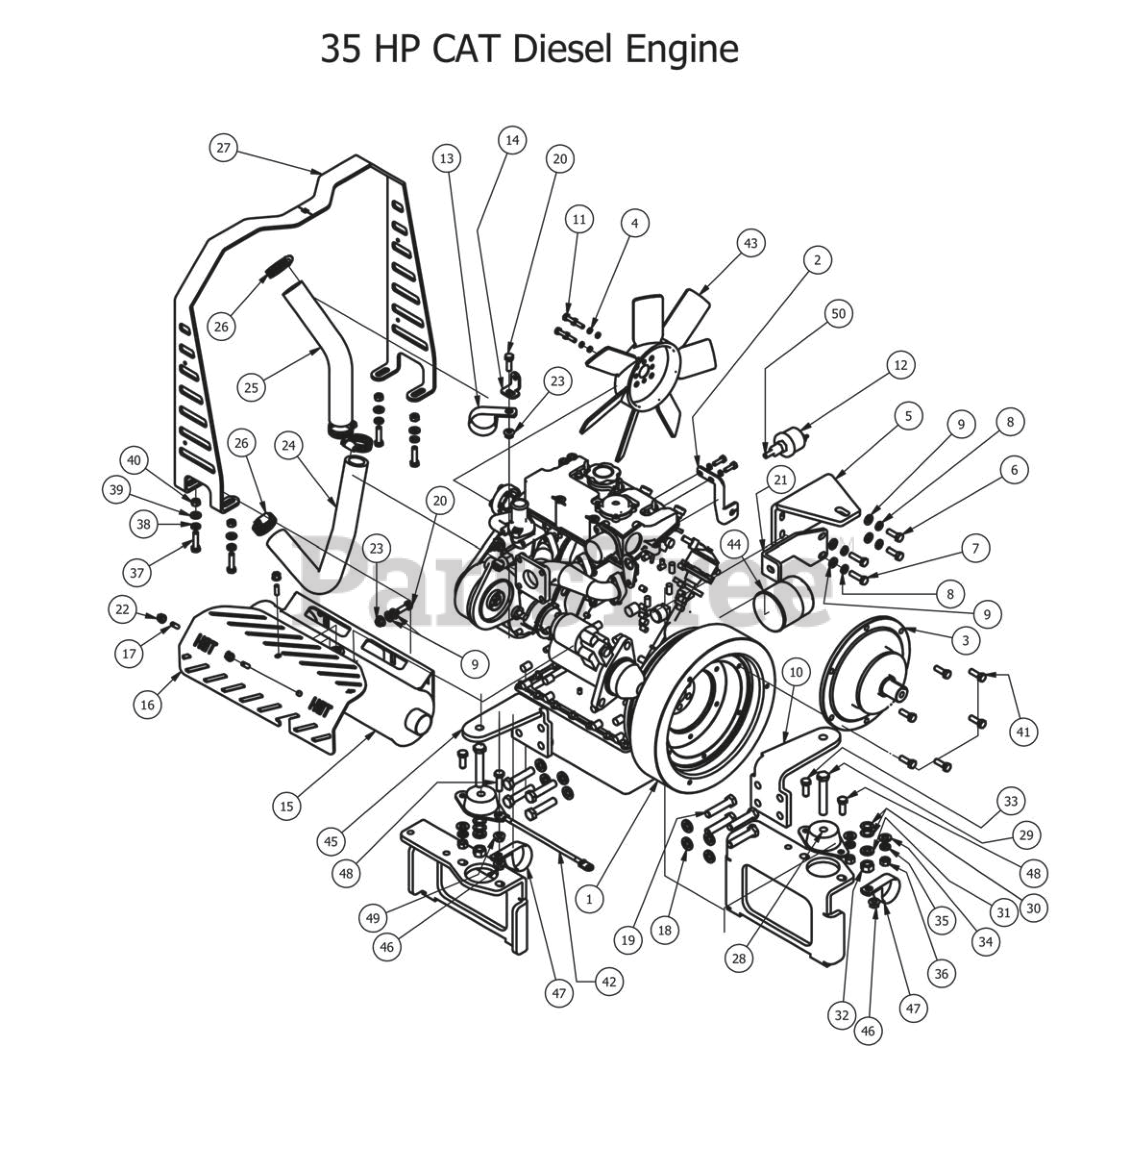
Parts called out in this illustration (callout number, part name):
1	35HP CAT Diesel Engine
2	Diesel Throttle Bracket (4 Tier)
3	Stub Shaft
4	1/4" Lock Washer
5	Air Cleaner Support Diesel
6	M8 x 1.25 x 25mm Hex Head Bolt
7	M8 x 1.25 x 30mm Hex Head Bolt
8	5/16" Lock Washer
9	5/16" Flat Washer
10	Diesel Motor Side Support Right
11	6mm x 20mm Bolt
12	Pressure Sender-2012 Gauge and Up
13	Diesel Clamp 1 3/4" Vinyl
14	Diesel Radiator Hose Clamp Bracket
15	28/35hp Caterpillar Muffler
16	Diesel Muffler Guard (35Hp)
17	1/4" x 3/4" Set Screw
18	1/2" Lock Washer
19	12mm Bolt- Diesel
20	5/16" x 1" Bolt
21	Muffler Brace Diesel
22	1/4-20 Nylon Insert flange Nut
23	5/16" Flange Nut
24	Bottom Radiator Hose for Diesel
25	Top Radiator Hose for Diesel
26	1 1/8" Hose Clamp
27	Hood Holder Diesel
28	Rubber Isolator
29	1/2" x 3" Hex Bolt
30	1/2" Brass Washer
31	1/2" Lock Washer
32	1/2" Hex Nut
33	3/8" x 1" Hex Bolt
34	3/8" Flat Washer
35	3/8" Lock Washer
36	3/8" Hex Nut
37	5/16" x 1 1/4" Hex Bolt
38	5/16" Lock Washer
39	5/16" Flat Washer
41	5/16-18 x 1 Button Head Bolt
42	Starter to Chassis Cable - Diesel-35 Hp
43	Engine Fan - Diesel
44	CAT Oil Filter
45	Diesel Side Motor Mount Left
46	3/8 Nylock Jam Nut 1/2 Nut
47	Diesel Clamp 1 3/4" Vinyl
48	3/8" x 1 1/2" Hex Bolt
49	3/8" Flange Nut
50	Brass Washer for Weld-on Hinge
